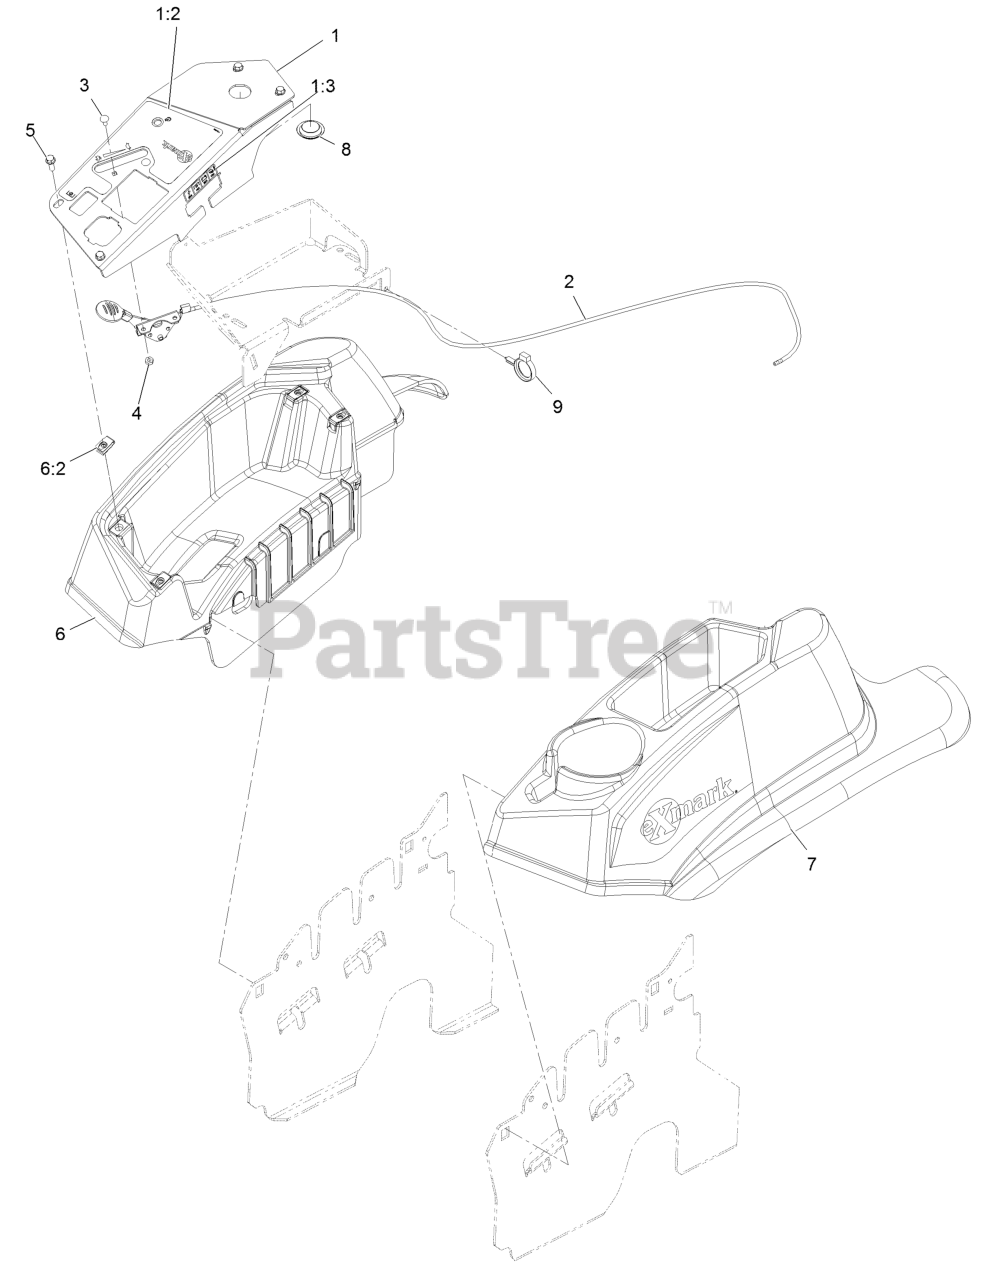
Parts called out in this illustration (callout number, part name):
1	ASM,Control Panel W/Decal
1:2	Decal-Control Panel Efi
1:3	Decal-Fuses
2	ASM,Throttle Cable
3	Bolt-Carriage #10-24 X 1/2
4	Nut-Nyloc #10-24
5	Screw-Machine 1/4-20 X 3/4
6	Console,RH As ASM
6:2	Nut-Retainer-Panel 1/4-20
7	Console, LH As
8	Plug,Plastic
9	Clamp-Hose
